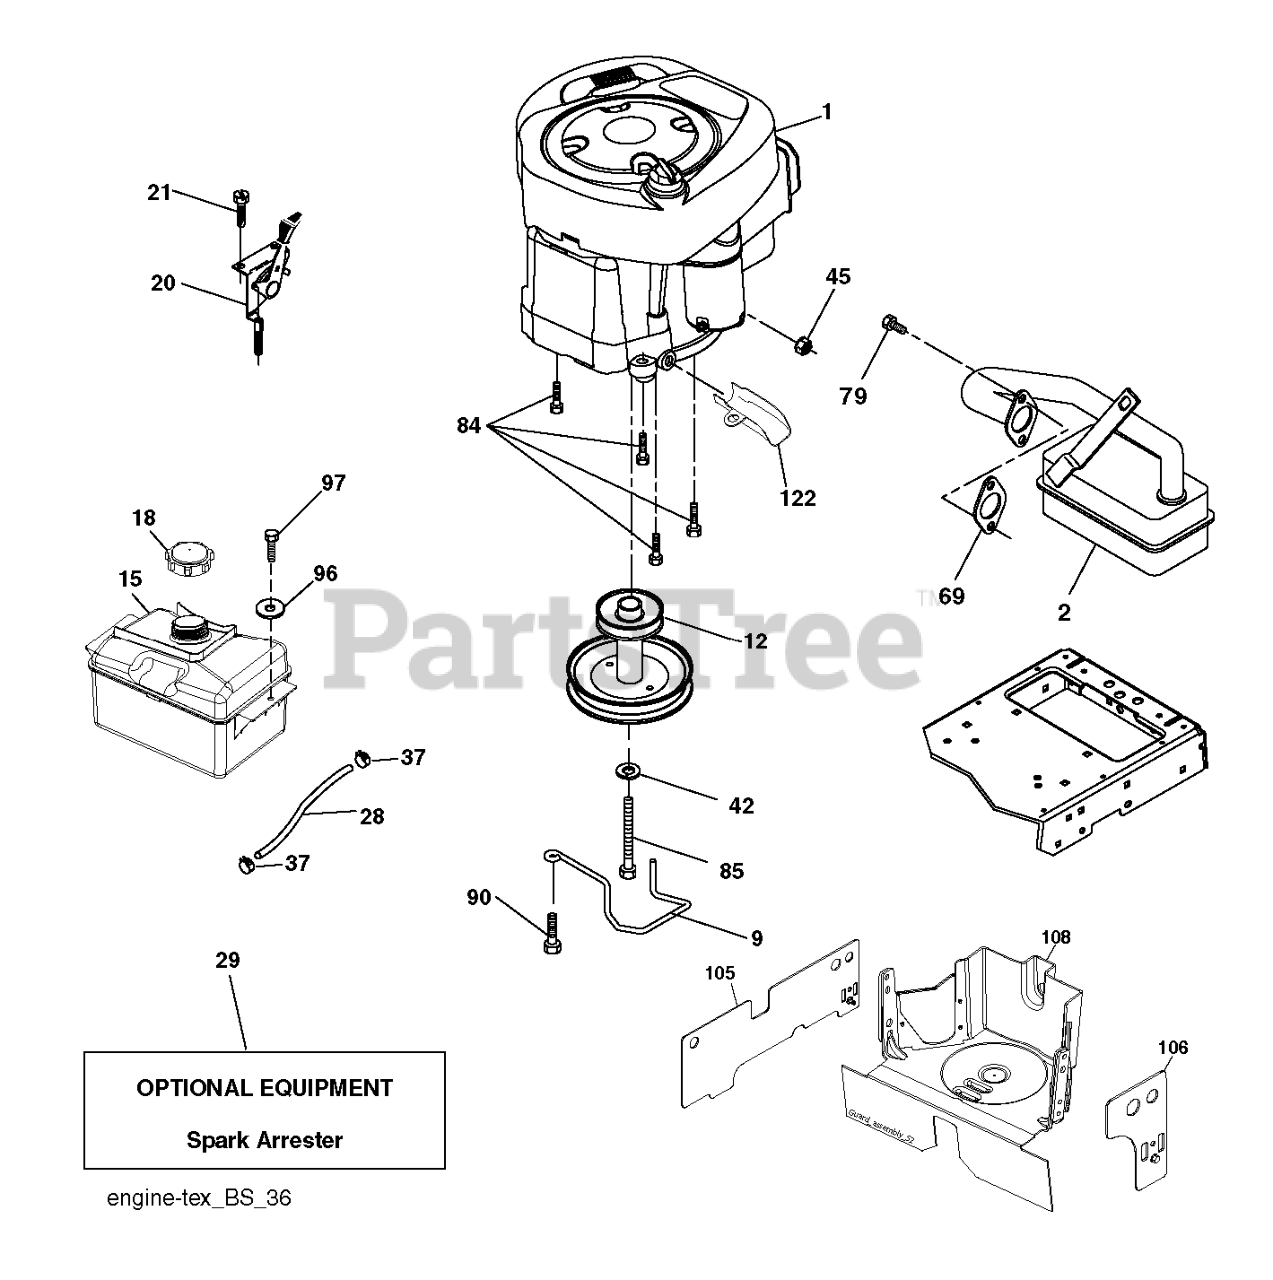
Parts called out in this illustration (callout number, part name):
2	MUFFLER.B&S.MODEL.21.11HP.OHV
9	KEEPER.BELT.ENGINE.3.25 (3 2)
12	PULLEY.ENG.CL.MECH.SLVR.LT/YT
15	RP TANK FUEL FRT 1.5 GAL
18	CAP ASM.FUEL.2.25"FR.
20	CONTROL.TH/CK.C.
21	SCREW.#10 X 0.750.BOS
28	LINE.FUEL.20
29	KIT.SPARK ARRESTOR 794945 B&S
37	HOSE CLAMP
42	LOCKWASHER
45	NUT
69	REPL BY 532 27 22-93
79	SCREW.SOCKET HD.5/16-1
84	SCREW.3/8-16
85	BOLT HEX 7/16-20X4-1/4"
90	SCREW 3/8-16X1
97	SCREW HEXWSHR 1/4-20X3/4
108	COVER PULLEY
122	EXTENSION DRAIN OIL
